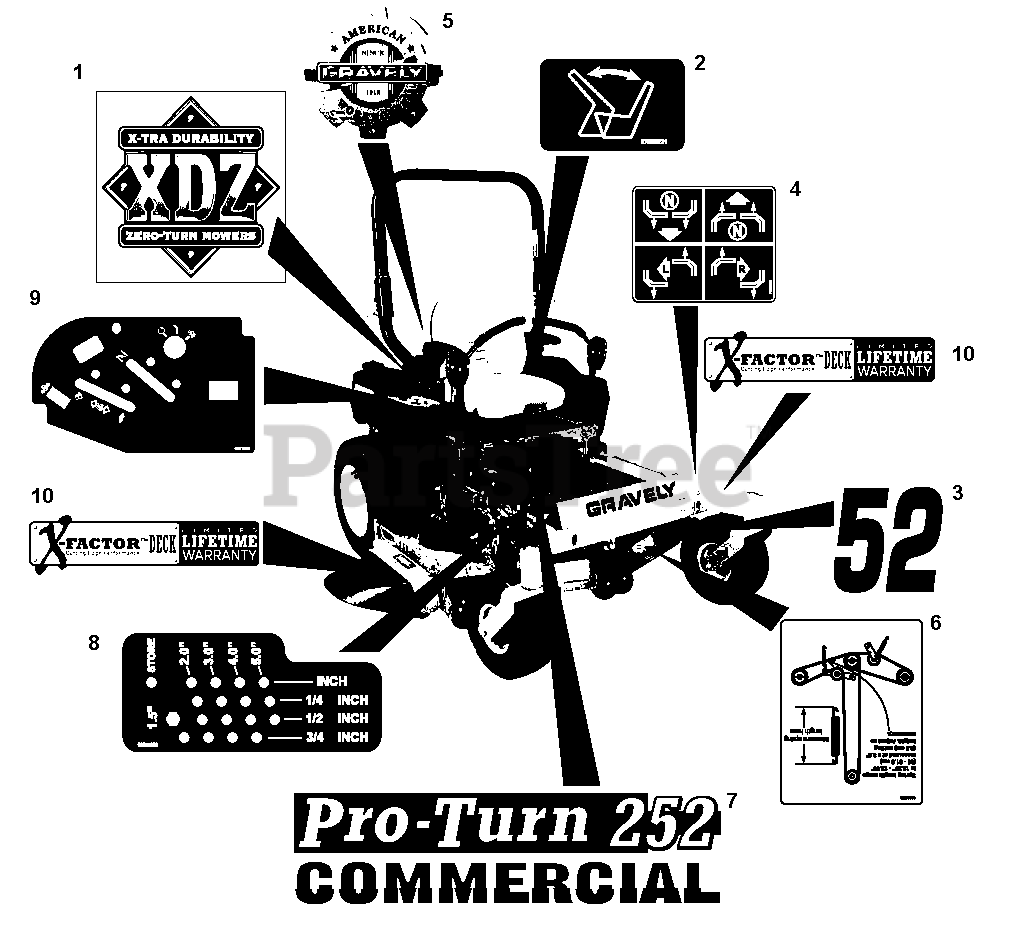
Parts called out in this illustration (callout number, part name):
1	Decal, XDZ
2	Decal, Seat Release
3	Decal, 52
4	Decal, Instructional- Steering
5	Decal, Gravely Heritage, Large
6	Decal, Belt Routing
7	Decal, Pro-Turn 252
8	Decal, Height of Cut
9	Decal, Control Panel
10	Decal, X-Factor Deck
